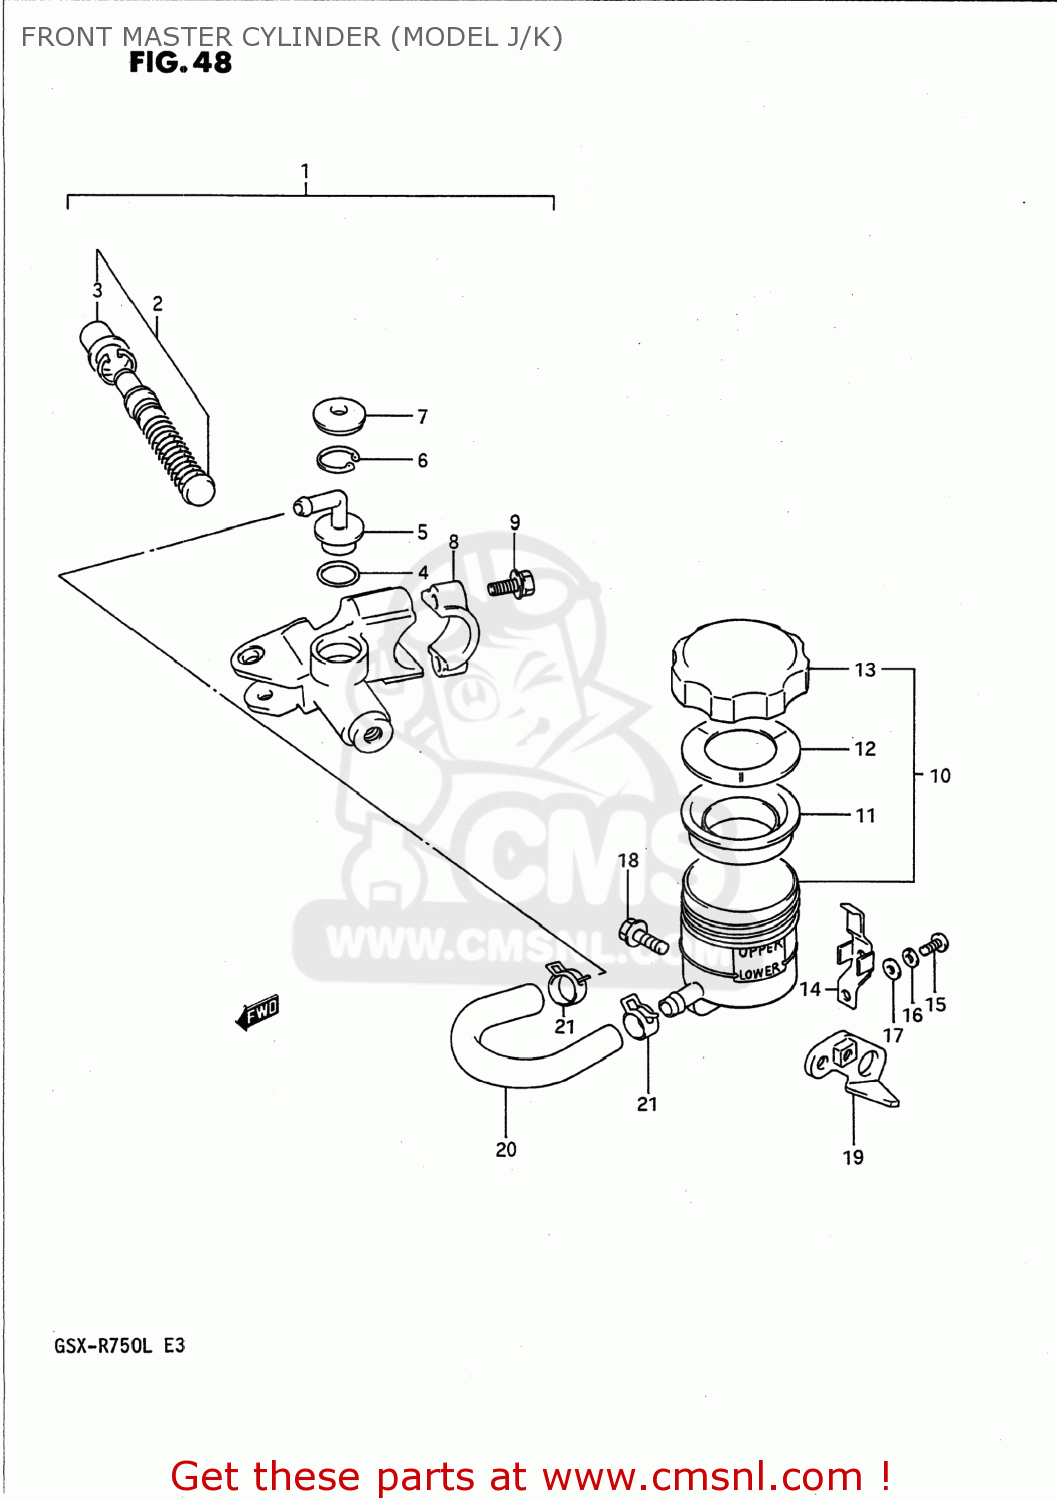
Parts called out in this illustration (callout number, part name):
1	CYLINDER ASSY,FR MASTER
2	PISTON & CUP SET
3	BOOT
4	O RING
5	CONNECTOR
6	CIRCLIP
7	COVER,DUST
8	HOLDER
9	BOLT
10	TANK ASSY,RESERVOIR
11	DIAPHRAGM
12	PLATE,DIAPHRAGM
13	CAP
14	PLATE,RESERVOIR TANK CAP
15	SCREW
16	WASHER,LOCK 4M
17	WASHER 4MM
18	BOLT 6X16
19	BRACKET COMP,RESERVOIR
20	HOSE,RESERVOIR TANK FR
21	CLAMP,RESERVOIR TANK FR
